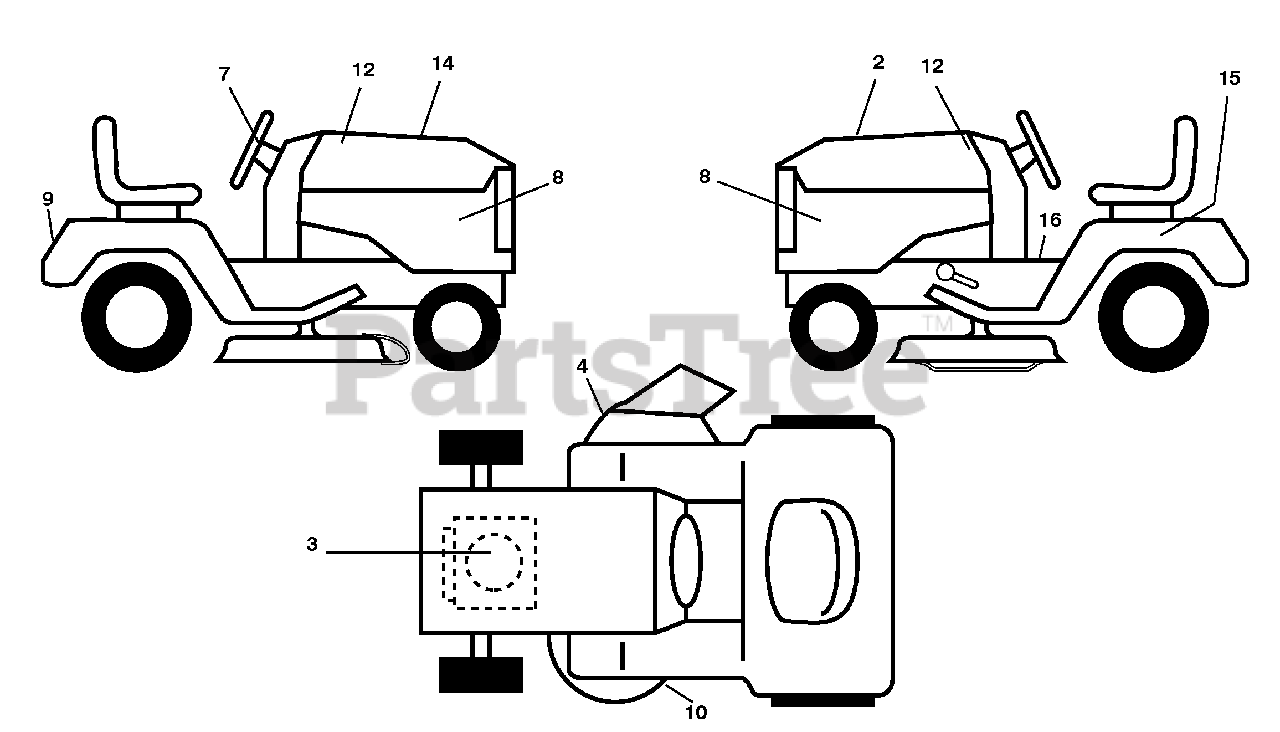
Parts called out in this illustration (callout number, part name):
2	Decal, Replacement
3	Decal, Engine HP
4	Decal Warning
7	Decal Ins Str Wh
8	Decal, Side Panel
9	Decal, Fender
10	Decal, V-Belt Sch.
12	Decal, Hood RH/LH
14	Decal, Hood Warning
15	Decal, Caution, Battery
16	Decal, Warning Fender
16	Decal, Handle Lft Height Adj.
16	Manual, Operator's (Spanish)
16	Manual, Operator's (English & French)
16	Manual, Parts (English & French)
